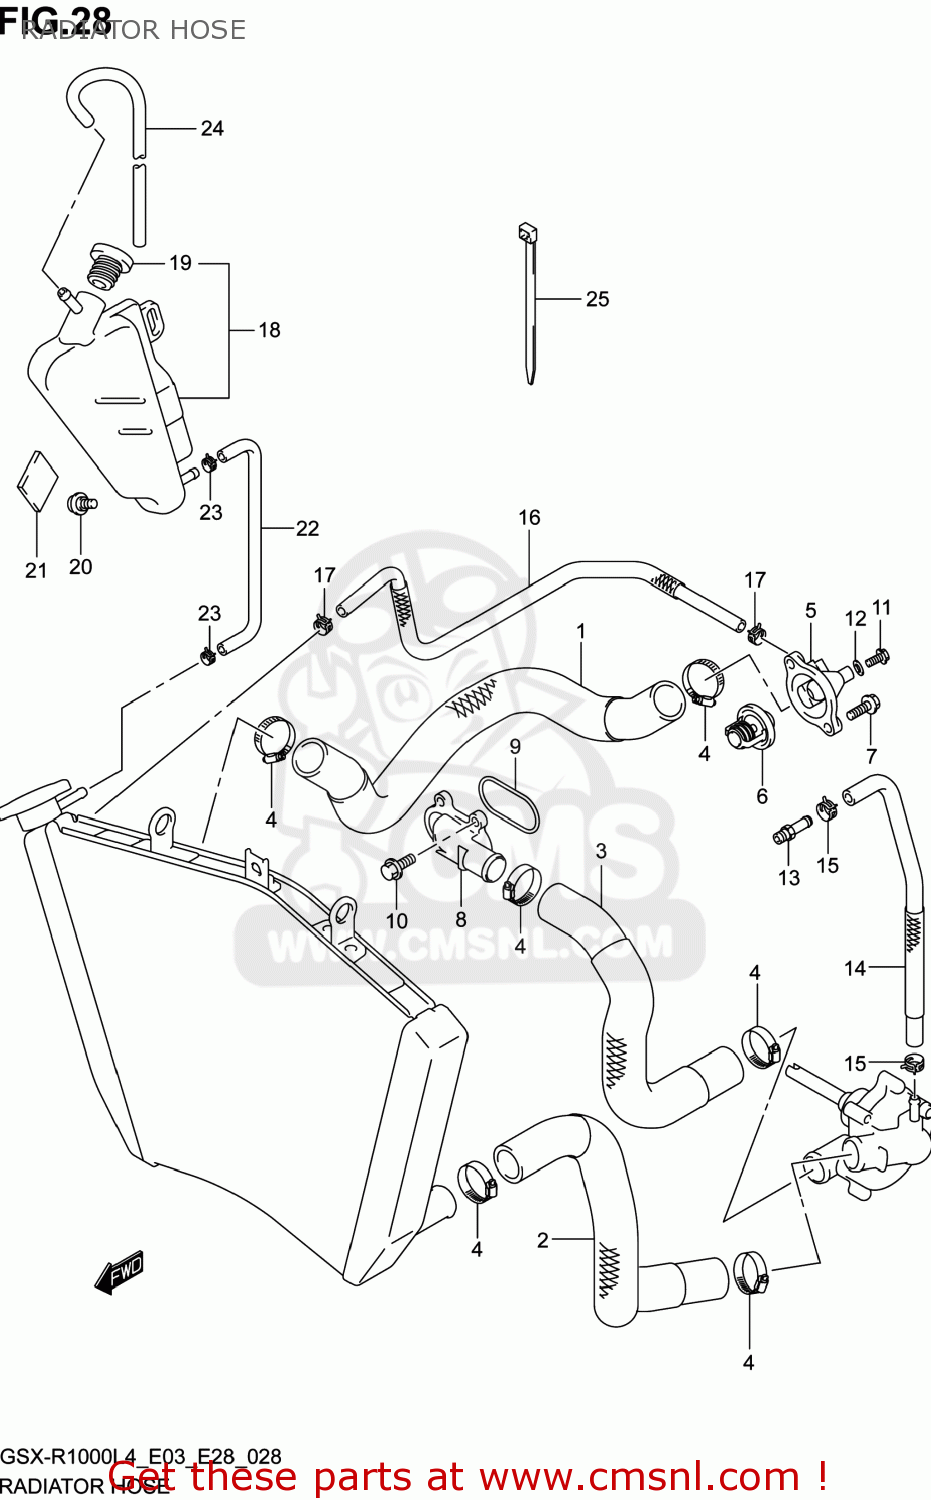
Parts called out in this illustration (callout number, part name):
1	HOSE,RADIATOR INLET
2	HOSE,RADIATOR OUTLET
3	HOSE,CYLINDER INLET
4	CLAMP
5	COVER,THERMOSTAT
6	THERMOSTAT,WATER
7	BOLT
8	CONNECTOR,CYLINDER WATER INLET
9	O RING,CYL WATER CONNECTOR
10	BOLT
11	UNION BOLT,AIR VENT
12	GASKET(6.4X11.5X0.8) (NAS)
13	BOLT UNION
14	HOSE,WATER BYPASS
15	CLAMP
16	HOSE,WATER AIR BLEED
17	CLIP
18	TANK ASSY,RESERVOIR
19	CAP,RESERVOIR TANK
20	BOLT(6X12)
21	CUSHION
22	HOSE,RESERVOIR TANK INLET
23	CLIP
24	HOSE,RESERVOIR TANK OVFL
25	CLAMP(L:100)
